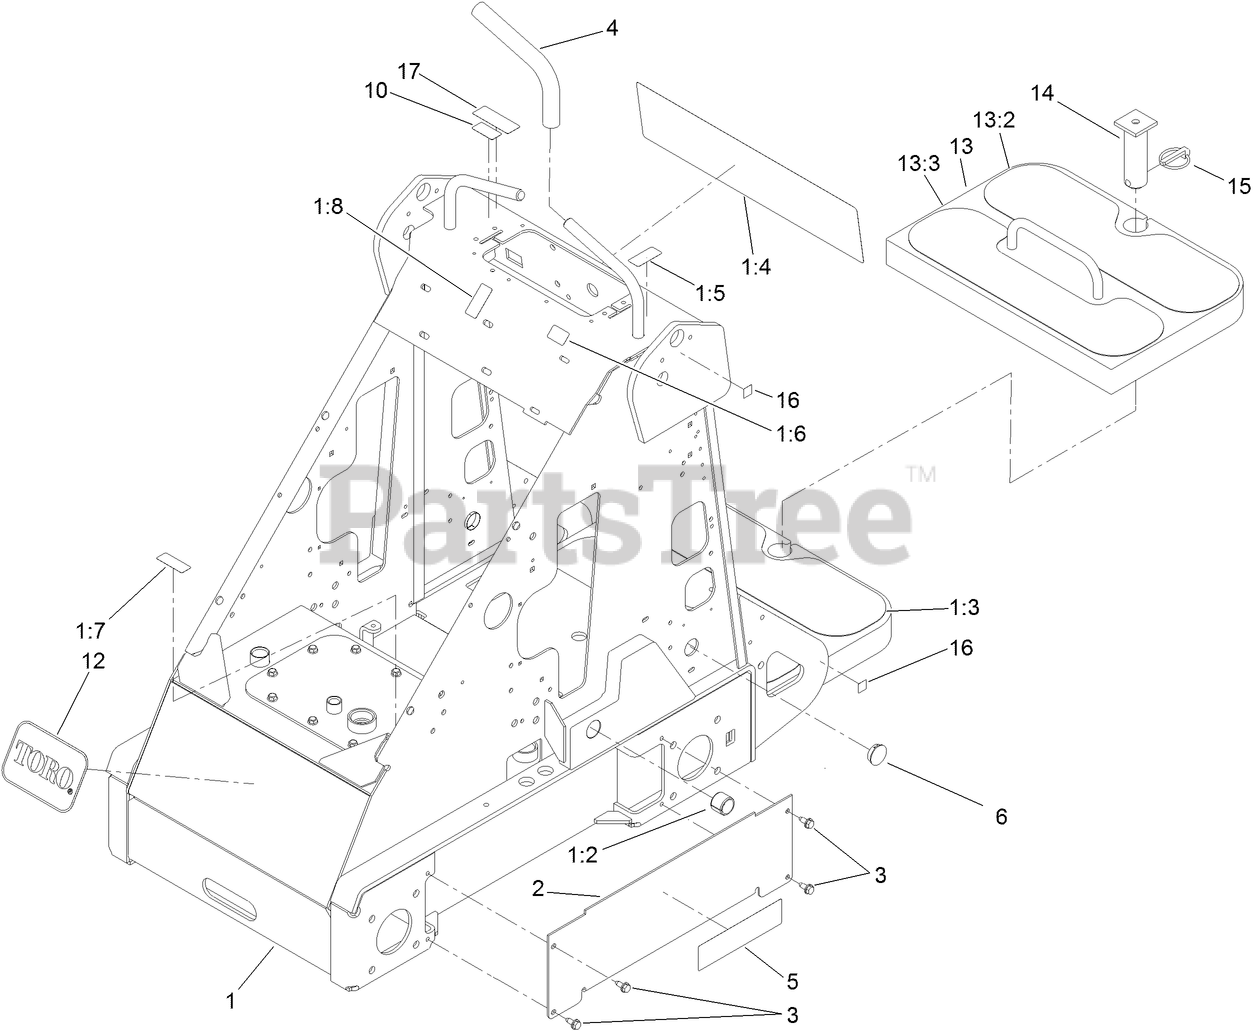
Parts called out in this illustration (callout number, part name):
1	FRAME ASM
1:2	BUSHING-TENSION
1:3	TREAD-FOOT
1:4	DECAL-CONTROL PANEL, CE
1:5	DECAL-THROTTLE
1:6	DECAL-LIMITER, SPEED
1:7	DECAL-OIL, HYD
1:8	DECAL-SELECTOR
2	COVER-HOSE
3	SCREW-HWHTF
4	GRIP-CUSHION
6	PLUG-HOLE
10	DECAL-PROTECTION, EAR
12	DECAL
13	COUNTERWEIGHT ASM
13:2	TREAD-FOOT
15	PIN-LYNCH
16	DECAL-POINT, LIFT
17	DECAL-ARRESTER, SPARK
